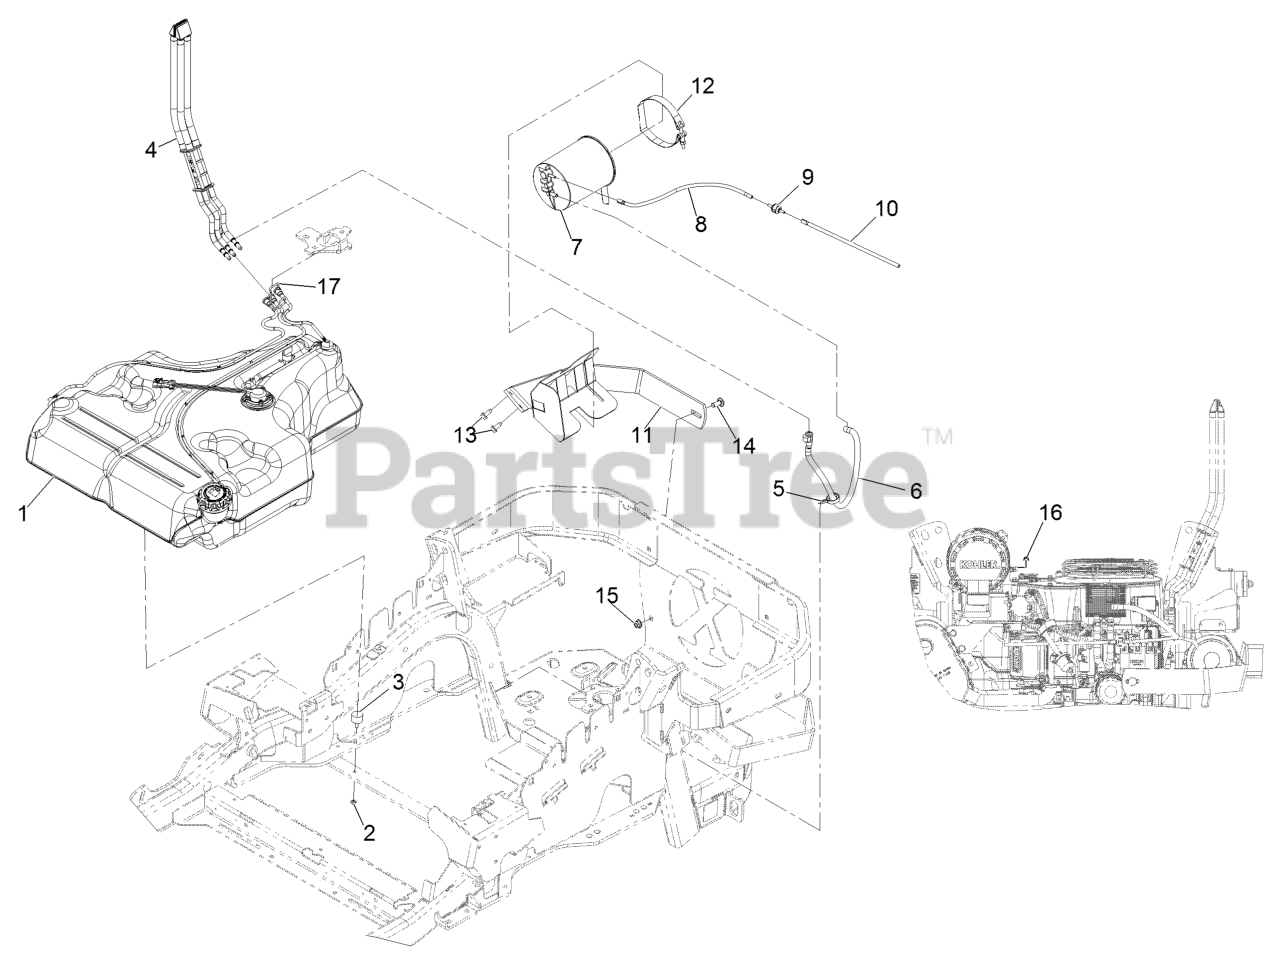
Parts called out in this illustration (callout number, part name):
2	NUT-JAM
4	FUEL MANIFOLD VENT ASM
5	CLAMP-HOSE
6	VENT HOSE ASM
7	CANISTER-CARBON, 1200CC
8	HOSE-VENT, FORMED
10	HOSE-VENT, FORMED
11	MOUNT-CANISTER
12	CLAMP, T-BOLT
13	Screw-HWH 5/16-18 X 3/4 Tf
14	SCREW-CARR
15	NUT-HF, NI
16	PLUG-PORT
17	RETAINER-LINE, VAPOR
